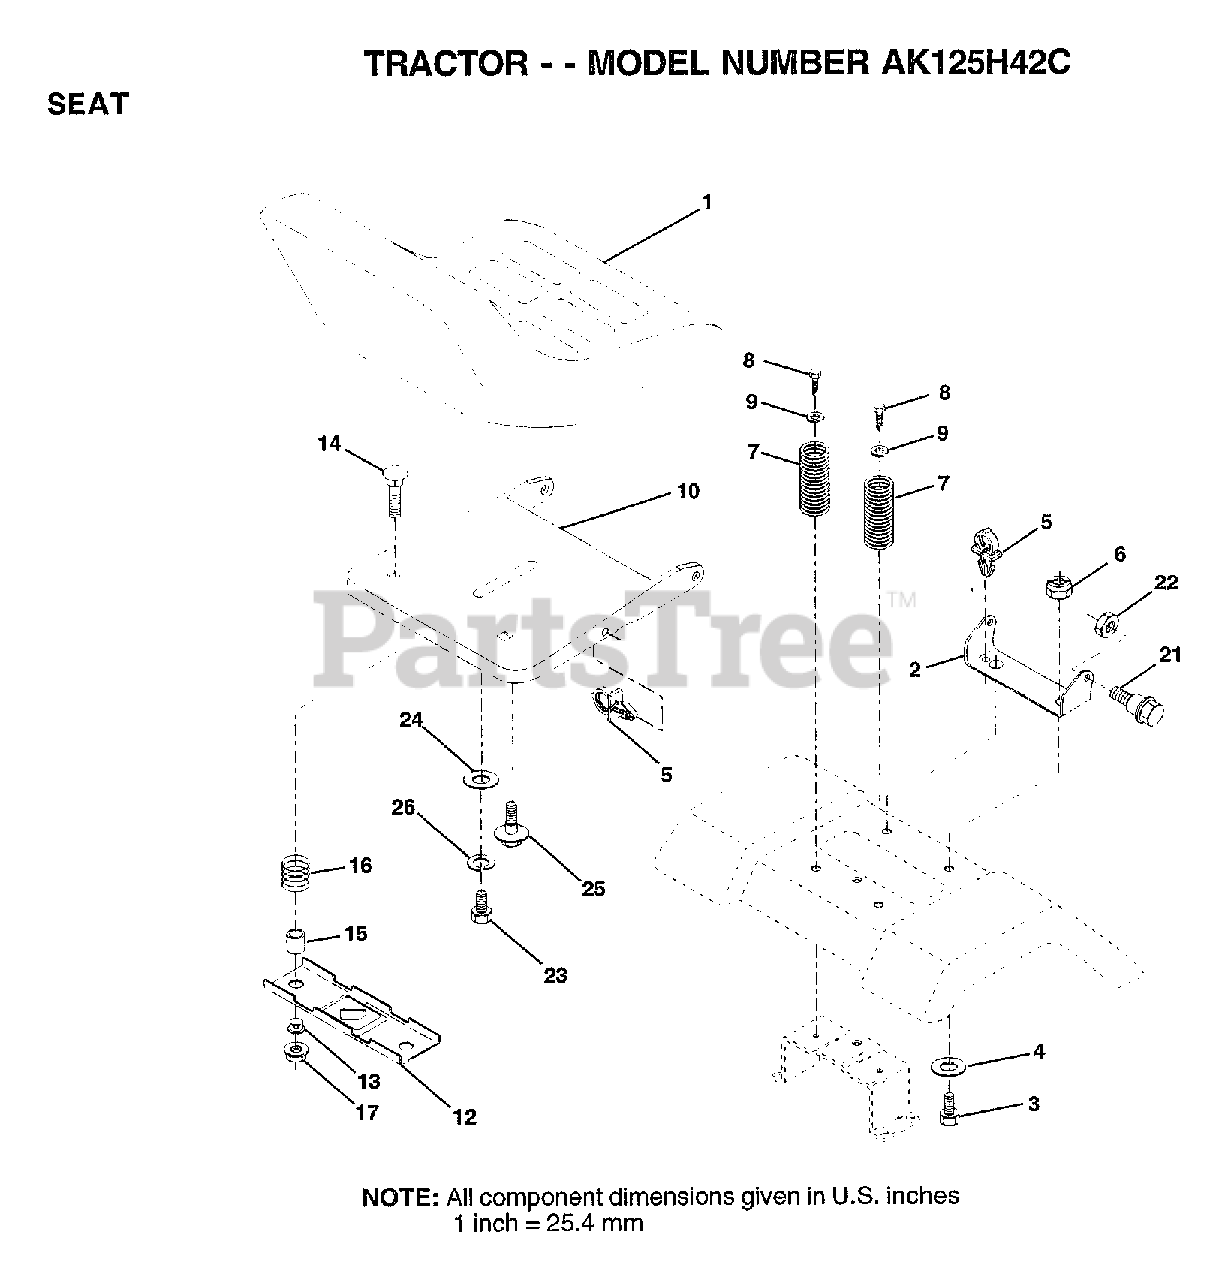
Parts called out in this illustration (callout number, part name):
2	BRACKET PVT SEAT
3	BOLT
4	WASHER PM
5	CLIP.PUSH-IN.HING
6	NUT
7	SPRING COMPRESSIO
8	SCREW
9	WASHER
10	PAN-SEAT
12	BRKT SWITCH
13	BUSHING
14	BOLT-RD HD SQ NK
15	SPLIT SPACER
16	SPRING
21	BOLT
22	NUT
23	BOLT HEX BLACK
24	WASHER
25	"BOLT,SHOULDER"
26	LOCKWASHER
